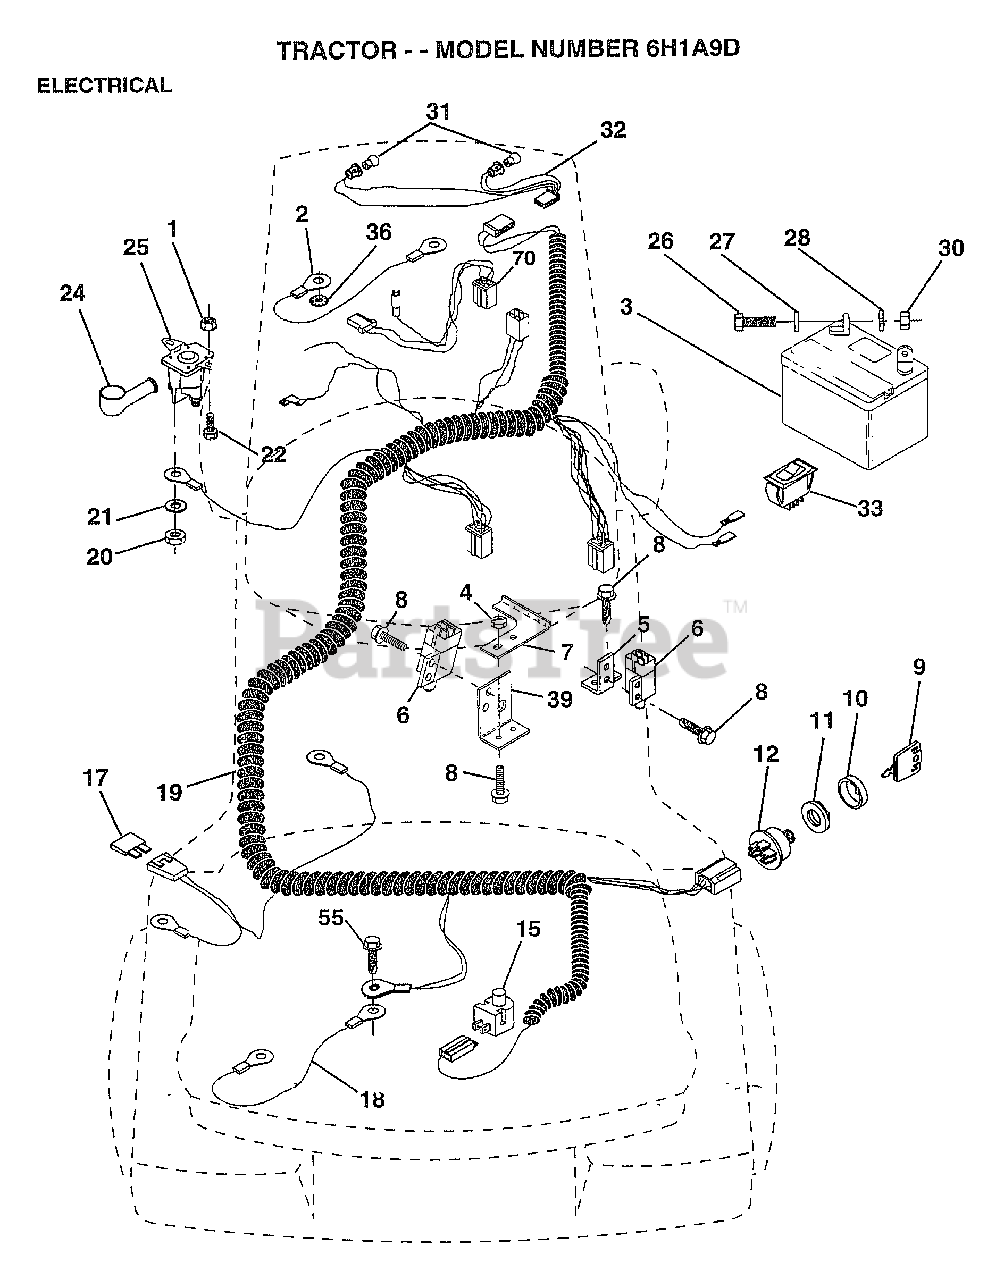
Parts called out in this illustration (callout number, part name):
1	NUT HXKEP 1/4X20
2	CABLE ASM.
4	LOCKNUT
5	BRACKET LT
6	SWITCH INTERLOCKT
7	KEEPER.ACTUAT.LR.
8	SCREW
9	KEY MLD GEN DELTA
10	COVER KEY SWITCH
15	SWITCH SEAT
17	FUSE HYT
18	CABLE ASSY
19	HARNESS.IGN.LR.
20	NUT
22	BOLT HXHD FIN
26	BOLT LT
27	WASHER
28	LOCKWASHER
31	HEADLAMP BULB
32	"HARNESS,LIGHT SOC"
33	SWITCH LT
36	LOCKWASHER
39	BRACKET SWT CLUTC
55	SCREW LT
70	HARNESS ENG DUAL
